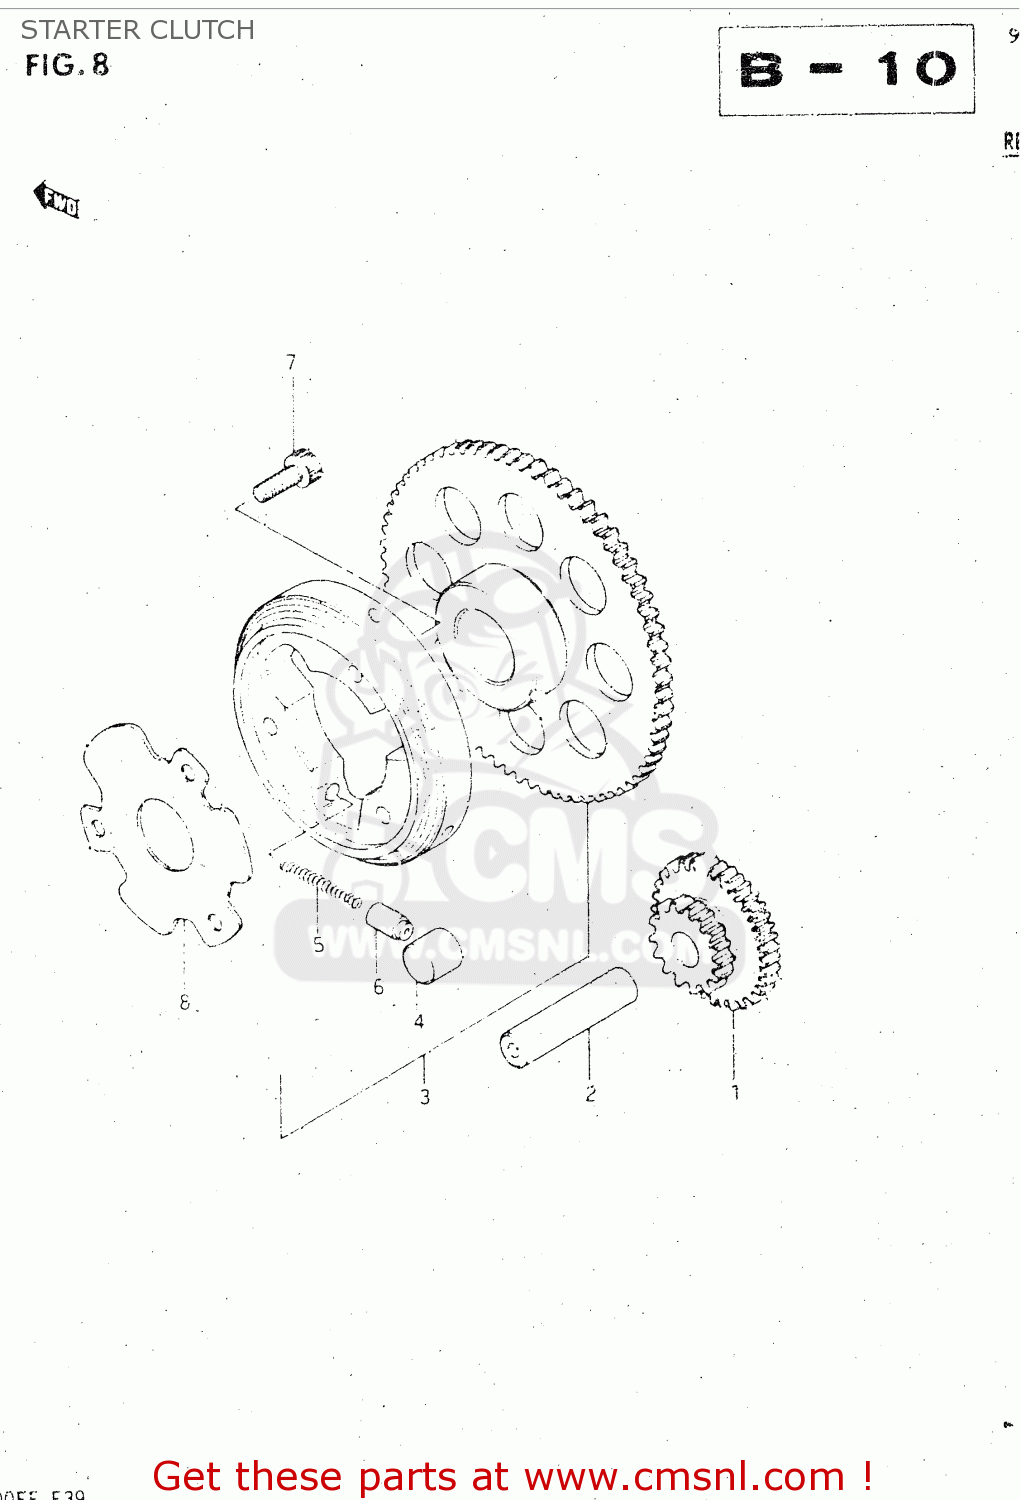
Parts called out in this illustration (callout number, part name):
1	GEAR,STARTER IDLE
2	PIN(7.4X13X56)
3	CLUTCH SET,STARTER
4	PIN(14X13)
5	SPRING
6	PIECE,PUSH
7	BOLT
8	SHIM,STARTER CLUTCH HUB
